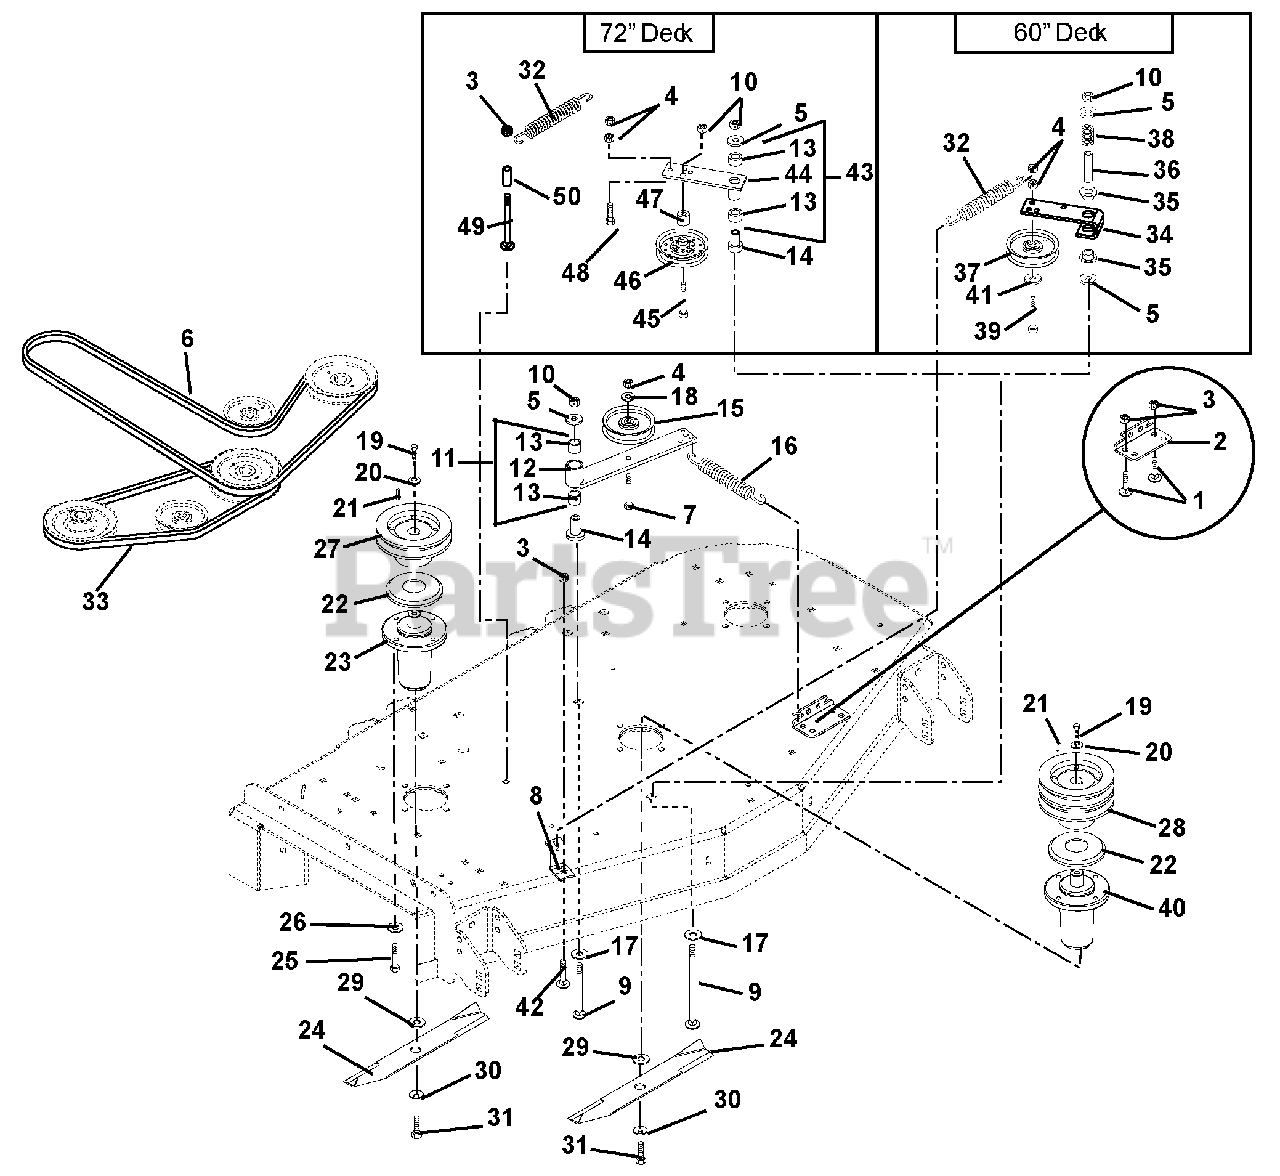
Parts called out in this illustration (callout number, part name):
1	Bolt, Round Head Square Neck .38-16 x .75 Grade 5
2	Bracket, Spring
3	Nut, Locking Top Flange .38-16 (016)
4	Nut, Locking Center .38-16
5	Washer, Flat Steel .531 x 1.25 x .10 (016)
6	V-Belt B-Section 63.40 x .625 (016)
7	Bolt-Round Head Square Neck .38-16 x 2.75 Grade 5
8	Anchor, Spring
9	Bolt, Round Head Square Neck .50-13 x 3.50 Grade 5
10	Nut, Locking Top Flange .50-13 (016)
11	Assembly, Idler Pivot Arm (Contains Items 12 & 13)
12	Weldment, Idler Pivot Arm
13	Bearing, 1.00 x 1.12 x .75
14	Bearing, Pedestal Powdered Metal (016)
15	Idler, Flat 4.00 x .38 (2.00 W)
16	Spring, Extension
17	Washer, Flat Steel .755 x 1.375 x .062
18	Washer, Flat Steel .375 x 1.125 x .065
19	Bolt, Hex .38-16 x 1.00 Grade 8
20	Washer, Cupped Serrated .375
21	Key, Square .25 x .25 x 1.00
22	Slinger, Dust
23	Assembly, Maintenance Free Spindle
24	Blade, Mower (017)
25	Bolt, Hex .38-16 x 1.00 Grade 5
26	Washer, Locking .38 x .094 Regular
27	Weldment, Spindle Sheave 6.00 (016)
28	Sheave, Double (6.25) (016)
29	Washer, Flat .64 x 1.81 x .25
30	Washer, Bellville .63 x 1.625 x .14
31	Bolt, Hex .62-18 x 1.75 Grade 8
32	Spring, Extension
33	V-Belt 5L-Section 49.97 x .672 (017)
34	Arm, Idler Pivot
35	Bushing, Flange .762 x 1.00 x .58 x 1.48 Nylon
36	Spacer .56 x .75 x 2.44 Steel
37	V-Idler, 4.00 x .38
38	Spring, Compression .085 x .80 x 1.00
39	Bolt, Hex .38-16 x 2.25 Grade 5
40	Spindle Assembly (Center)
41	Washer, Flat Steel .406 x .812 x .065
42	Bolt, Round Head Square Neck .38-16 x 1.00 Grade 5
43	Assembly, Idler Arm Guard Drive (Includes Items 13 and 44) (017)
44	Weldment, Idler Arm Ground Drive (017)
45	Bolt, Hex .38-16 x 6.00 Grade 5 (017)
46	Idler, Flat Pulley 6.75 x .51 (017)
47	Spacer .513 x .748 x .62 (017)
48	Bolt, Hex .38-16 x 1.25 Grade 5 (017)
49	Bolt, Round Head Square Neck .38-16 x 2.75 Grade 5 (017)
50	Spacer .38 x .625 x 1.50 (017)
